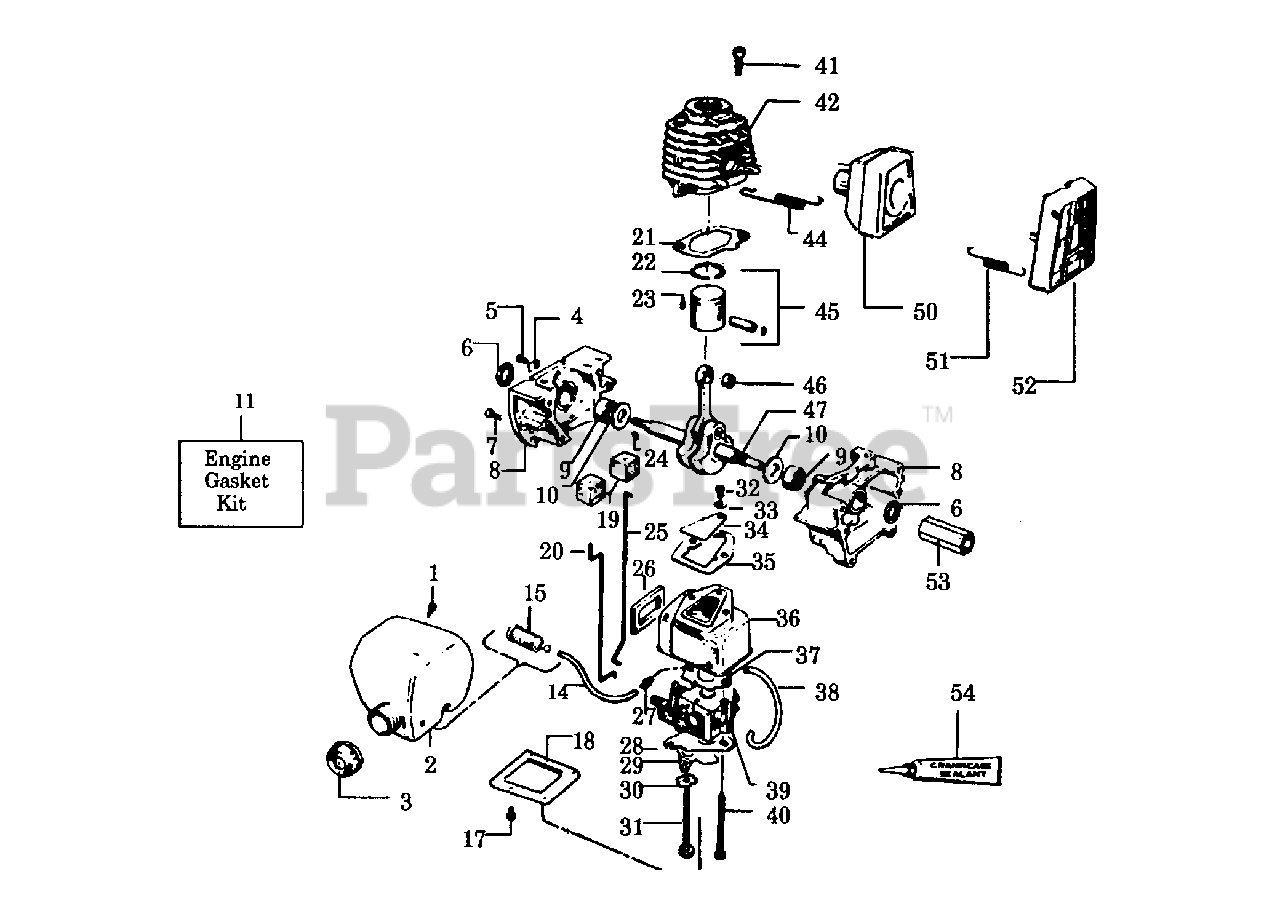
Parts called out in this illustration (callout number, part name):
1	Check Valve Duck Bill
2	Fuel Tank Ass'y.
3	Fuel Cap Ass'y. (Inc."O" Ring)
4	Choke Wire Clamp
6	Crankcase Seal
8	Crankcase Ass'y. (Inc.6,7, & 9)
9	Crankcase Bearing
11	Engine Gasket Kit
14	Fuel Line-Model XR-20-Type 1 & 2
15	Model XR-20-T 1 & 2
15	Model XR-20-T 3;Model XR-20-T 1
18	Carburetor Case Cover
19	Choke Wire Throttle Boot
20	Choke Wire
21	Cylinder Gasket
22	Piston Ring
23	Wrist Pin Retainer
24	Flywheel Key
25	Throttle Wire
26	Carburetor Case Seal
27	Model XR-20-T1 & 2
27	Model XR-20-T3; Model XR-20T-T1
28	Choke Wire Guide Plate
29	Choke Shutter
30	Wave Washer
34	Reed Valve
35	Gasket
36	Carburetor Housing
37	Carburetor Gasket
38	Line Kit
39	Carburetor
42	Cylinder
44	Muffler Detachment Spring
45	Piston Kit (Inc.22,23,Pin)
46	Wrist Pin Bearing
47	Crankshaft & Rod Ass'y.
50	Model XR-20T
51	Muffler Guard Spring
52	Muffler Guard
53	Drive Adaptor
54	Crankcase Sealant
